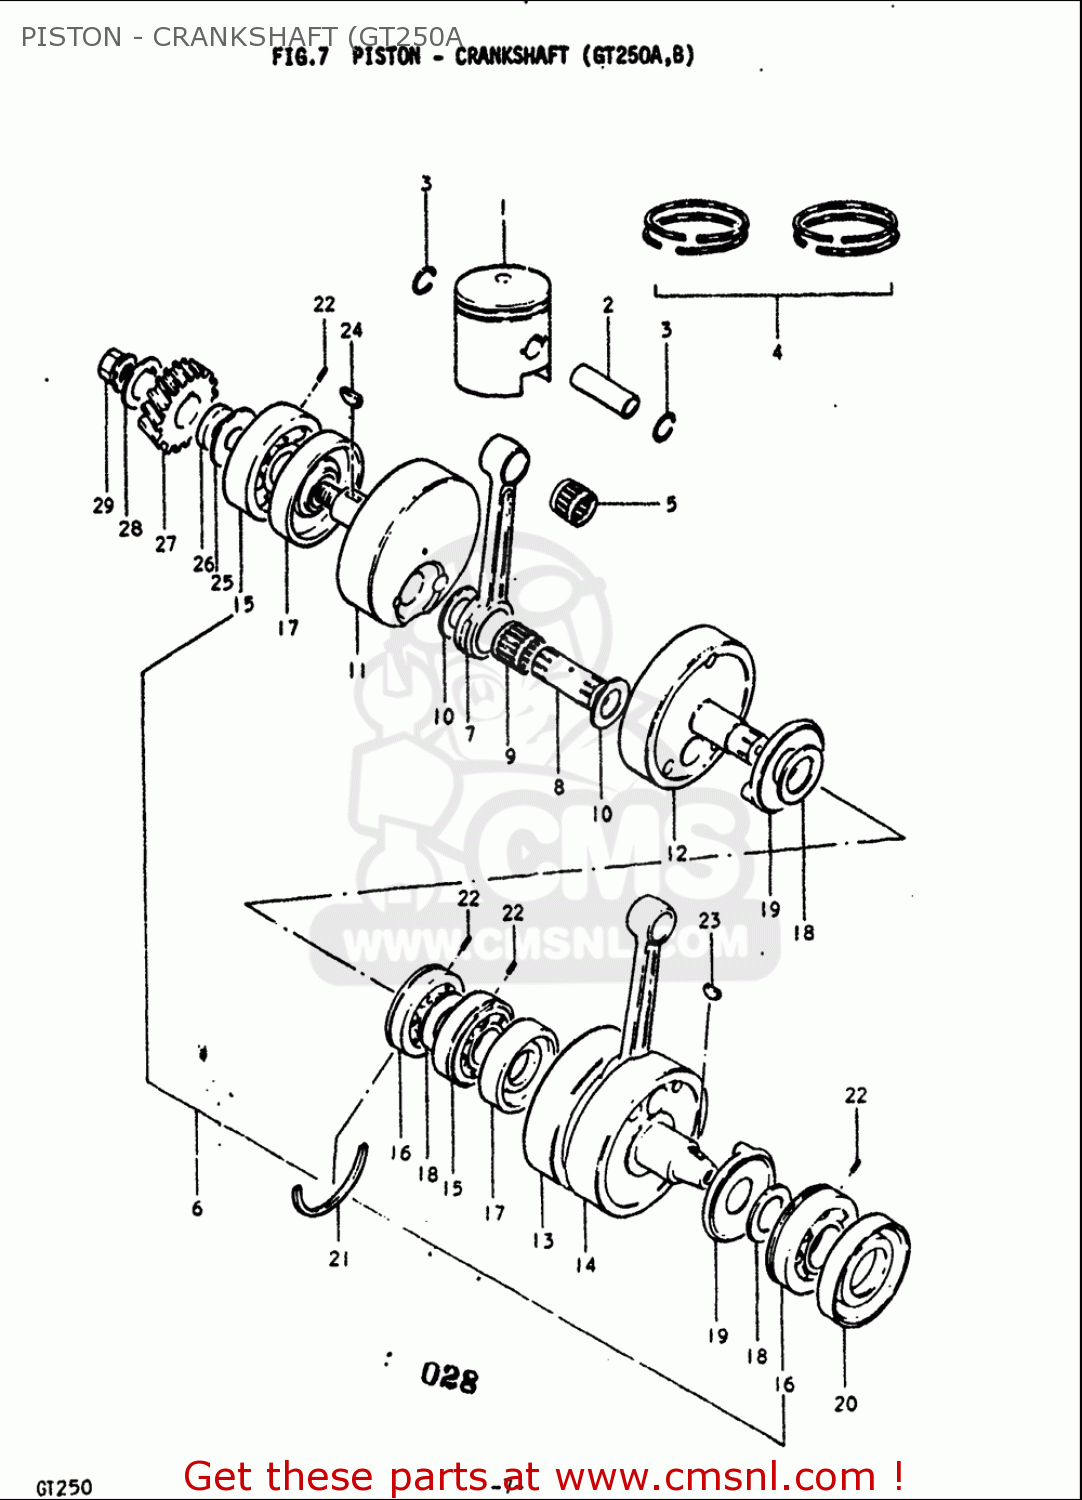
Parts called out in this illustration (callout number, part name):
1	PISTON SET(OS:0.5)
2	PIN,PISTON 14MM
3	RING,SNAP 14MM
4	RING SET,PISTON
5	BEARING(14X18X19.8)
7	CONNECTING ROD
9	BEARING(20X26X16.7)
10	WASHER (20X34X1)
16	BEARING(25X65X17)
20	SEAL,OIL(25X65X12)
22	ROLLER(4X13.8)
23	KEY
24	KEY
25	WASHER(20X48X1)
28	WASHER
